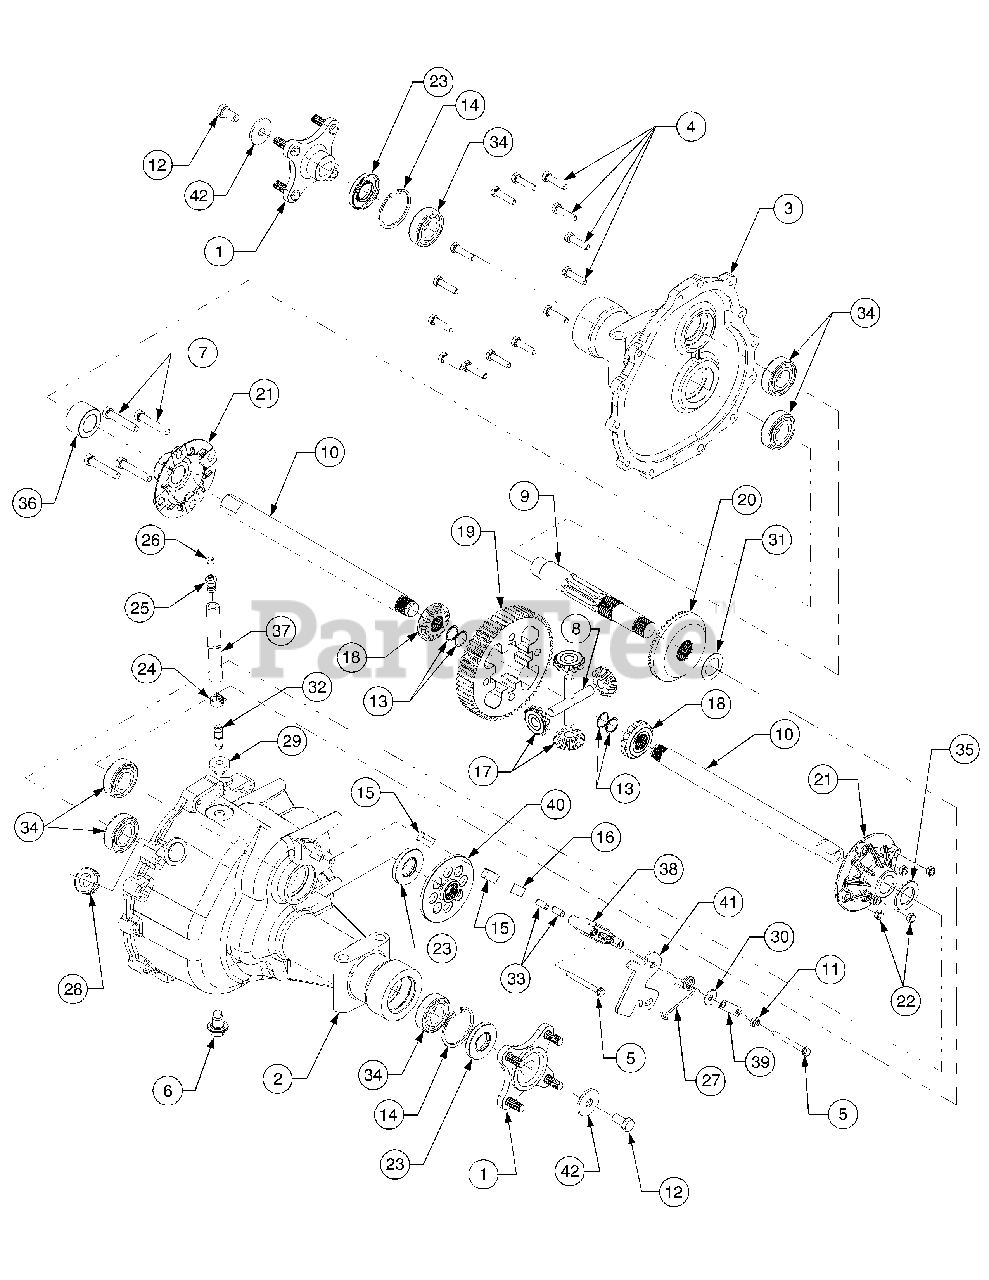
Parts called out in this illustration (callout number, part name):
1	Hub Ass’y, Wheel
2	Housing, RH Transmission
3	Housing, LH Transmission
4	Screw, Hex Cap Lock, 5/16-18 x 1.25 GR5
5	Screw, Hex Wash Hd. Tapp, 1/4-20 x 2.375
6	Screw, Plug, M14 x 1.5 x .827
7	Screw, Hex Cap Lock, 3/8-16 x 2.0 GR5
8	Shaft, Cross, .50 x 3.005
9	Shaft, Output, 9T
10	Shaft, Axle
11	Nut, Hex Nylon Lock, 5/16-24
12	Screw, Hex Cap Lock, 3/8-16 x .75 GR5
13	Ring, Retaining
14	Ring, Retaining
15	Pad, Brake
16	Plate, Puck
17	Gear, Miter, 10T
18	Gear, Miter, 14T
19	Gear, Differential Spur, 60T
20	Gear, Bevel, 54T
21	Housing, Differential w/Thru Holes
22	Nut, Hex Insert Jam GR5, 3/8-16
23	Seal, Oil, 1.0 x 2.047 x .2755
24	Clamp, Hose
25	Vent, Plastic
26	Cap, Plastic Vent
27	Spring, Torsion
28	Grommet, Rubber, .75 x 1.063
29	Grommet, Rubber, .362 x .56
30	Washer, Flat, .343 x .88 x .062
31	Washer, Thrust, 1.007 x 1.542 x .03
32	Fitting, Tube
33	Pin, Brake Actuating
34	Bearing, Ball (6205-1)
35	Spacer, Axle, 1.007 x 1.665 x .141
36	Spacer, Axle, 1.007 x 1.665 x .989
37	Tube, Transmission Breather
38	Yoke, Brake
39	Bracket, Brake Anti Rotation
40	Disc, Brake
41	Arm, Brake Actuater
42	Washer, Flat, .39 x 1.5 x .134
